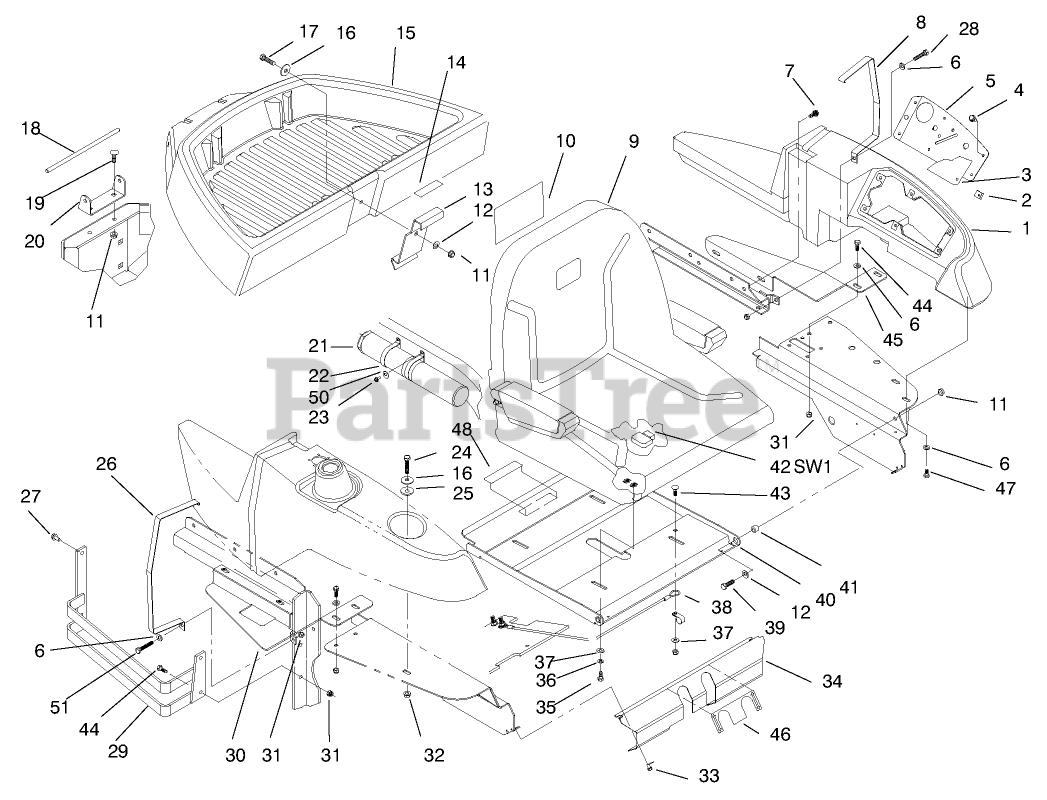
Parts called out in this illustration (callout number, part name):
1	CONSOLE
2	CLIP-TINNERMAN
3	Decal-Instrument
4	SCREW-PPH
5	Panel-Instrument
6	WASHER-PLAIN
7	SCREW-HWHTF
8	STRAP-CONSOLE
10	DECAL
11	NUT-LOCK, NI
12	WASHER-FLAT
13	LATCH - UTILITY BOX B
14	DECAL - NO RIDERS
15	BOX - UTILITY
16	WASHER
17	SCREW-HH
18	PIN - PIVOT,UTILITY BOX
19	BOLT-CARR
20	HINGE - DUMPBOX B
21	TUBE-MANUAL
22	CLAMP-R
23	RIVET-BLIND
24	SCREW-HH
25	BUSHING-FLANGE
26	STRAP-TANK, FUEL
27	SCREW-HWHTF
28	SCREW-HH
29	Bumper ASM
29	BUMPER ASM
30	PLATE-SUPPORT, TANK
31	NUT-LOCK, NI
32	NUT-HHF, WHIZ
33	SCREW-HWH
34	PLATE - COVER, FRONT
35	SCREW-HH
36	WASHER-LOCK
37	WASHER-FLAT
38	Cable
39	SCREW-HH
40	SEAT PLATE ASM
41	SPACER-WHEEL
42	SWITCH-SEAT
43	BOLT-CARR
44	SCREW-HH
45	PLATE - CONSOLE SUPT R
46	DECAL - OPERATION
47	SCREW-HH
49	DECAL-HOT SURFACE
50	WASHER-FLAT
51	SCREW-HH
52	LATCH ASM
53	PIN-HAIR
56	PLUG - DOME 1.125 DIA
